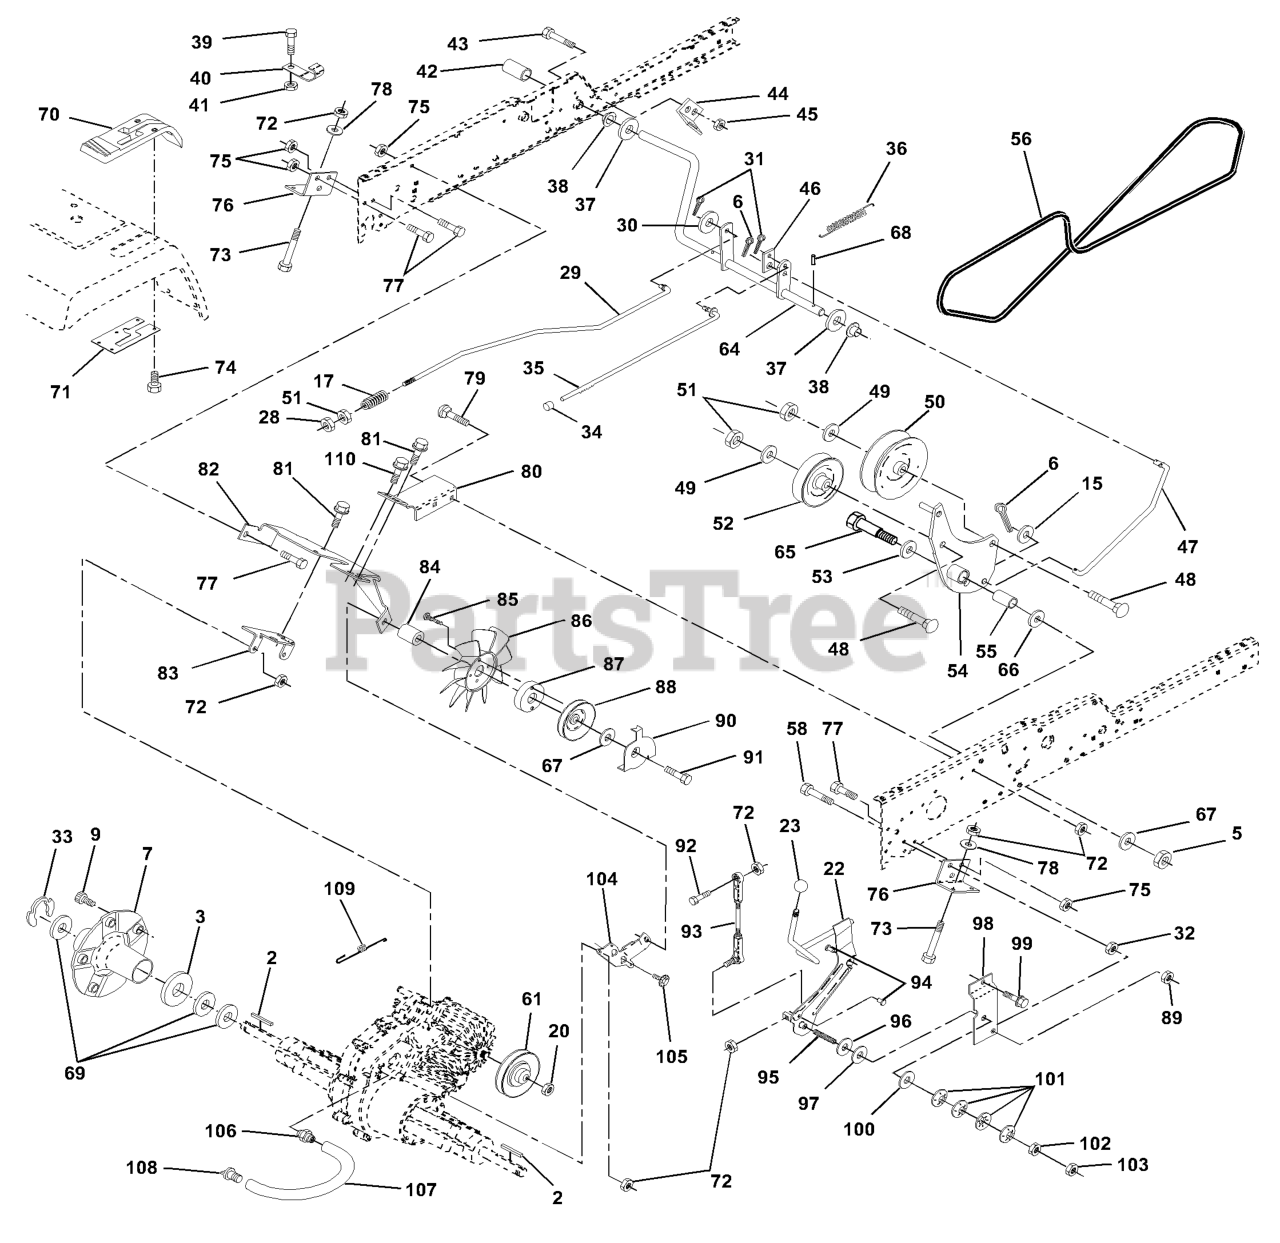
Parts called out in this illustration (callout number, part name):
2	KEY 1/4 X 2.5
6	COTTER PIN
7	HUB ASMBLY
9	HUB BOLT
15	WASHER
17	SPRING.ROD.BRAKE
20	NUT.HEX.1/2-20
22	SHAFT ARM ASMBLY
23	KNOB.DELUXE.(PISTOL.GRIP).BLAC
28	NUT
30	WASHER
31	COTTER PIN
33	E RING HYT
34	PLUNGER CAP
35	PARKING BRAKE ROD
36	SPRING EXTENSION
39	Screw Fin #10-24 x 1
40	ACT-SWITCH T
41	LOCKNUT
42	COVER, PEDAL (1 2)
43	BOLT.HEX.1/4.X.3/4.DICHROMATE
44	BRKT SWITCH GT
45	LOCKNUT.NYLOC.1/4-20
46	RETAINER SPRING
47	CLUTCH ROD
49	Washer 13/32 x 7/8 x 13 Ga
50	FLAT IDLER PULLEY
51	NUT
52	PULLEY.IDLER.V.
54	CLUTCH ARM ASSY
55	BEARING LT (2 2)
58	BOLT.HEX.7/16-14.FINISHED
64	PEDAL SHAFT
66	WASHER.BLADE
67	WASHER
68	ROLL PIN STD
70	CONSOLE
71	PLATE SHIFT CONSOLE
72	NUT.71038.31-18.HEX.NYLOCK
73	Bolt Fin Hex 5/16-18 x 3
74	SCREW.HI-LO.CONSOLE
75	Nut Lock Hex 7/16
76	BRACKET TRANSAXLE
77	BOLT
79	BOLT.CARR.5/16-18X5/8.SHORT
80	TORQUE BRACKET RH
81	SCREW
82	BRACKET
83	STRAP TORQUE MID
85	Screw #10-24 x 1-1/4
86	FAN 7" HYDRO
87	ADAPTOR.FAN.TRANSAXLE.VGTH
88	IDLER PULLEY
89	Nut, Crownlock 7/16-14
90	KEEPER.BELT
91	SCREW.HXWSH.3/8
92	BOLT
93	LINK ASM SHIFT
94	FASTENER.XMAS.TREE
95	Screw Set 5/16-18 x 1.75
98	SHIFT BRACKET
99	SCREW LT
102	NUT
103	JAM NUT TI
104	BRACKET IDLER
105	SCREW CRT
106	VENT FITTING
108	VENT CAP 70109
109	RETURN SPRING
110	HINGE SCREW
